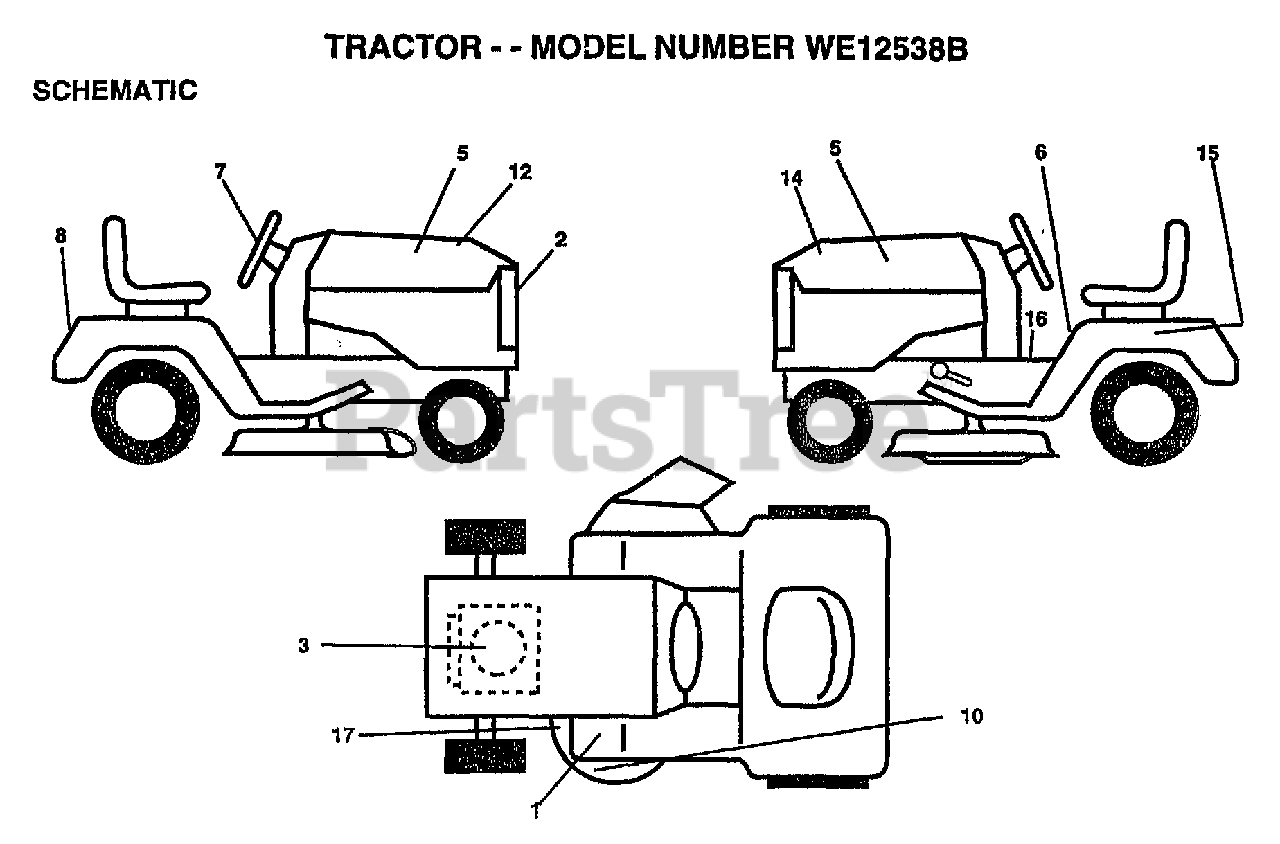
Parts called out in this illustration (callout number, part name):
2	"DECAL GRILLE,LENS"
3	DECAL, HP ENGINE
5	"DECAL.PANEL,SIDE"
6	"DECAL DANGER,FEND"
7	"DECAL INS,STRG WH"
8	DECAL-FENDER
9	DECAL CHASSIS SPEED DECK
11	DECAL.DANGER.CUTF
12	"DECAL HOOD,RH"
14	DECAL HOOD LH
15	DECAL.BATRY.3-3908
16	"DECAL DASH,OPER."
17	DECAL
18	DECAL.EURO.ST.CE.
